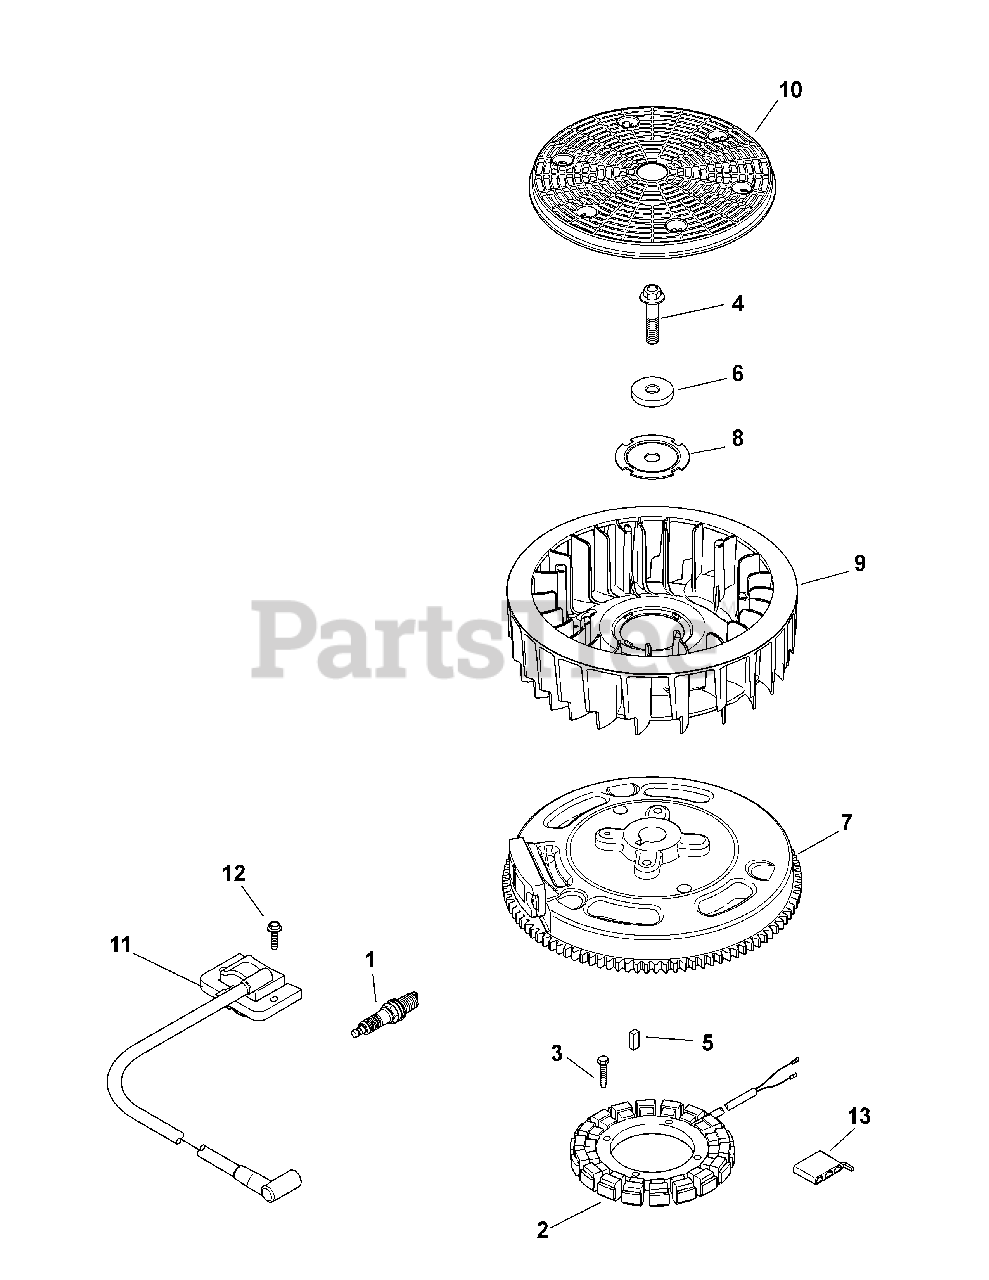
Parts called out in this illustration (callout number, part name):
1	Spark Plug
2	15 Amp Stator Kit
3	Screw, M5 x 0.8 x 25
4	Hex Flange Screw
7	Flywheel Assembly
8	Fan Mounting Plate
9	Fan
11	Module Ignition Kit
12	Screw, M5 x .8 x 20
